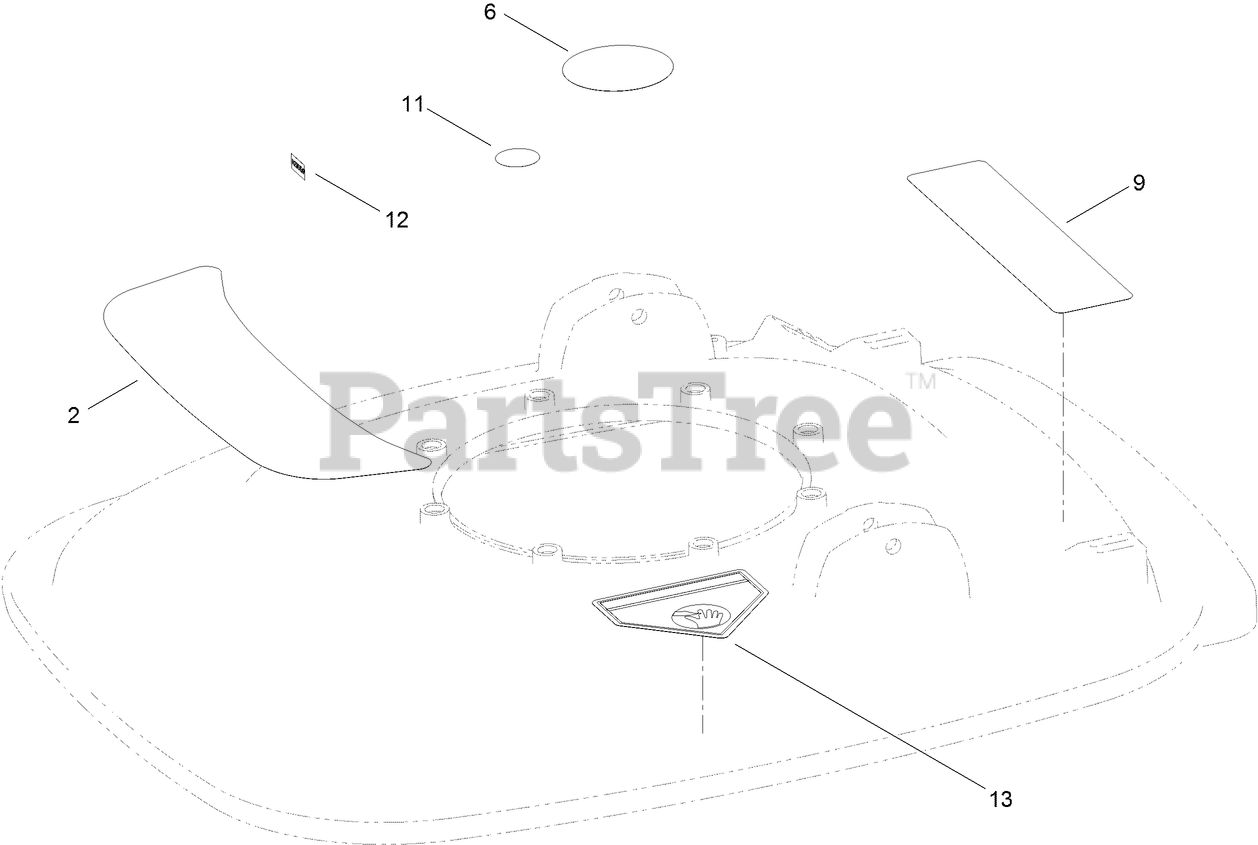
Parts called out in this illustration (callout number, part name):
2	DECAL-HOVER PRO
6	DECAL-ENGINE
9	DECAL-WARNING
11	DECAL
12	DECAL-STOP
13	DECAL-DANGER
